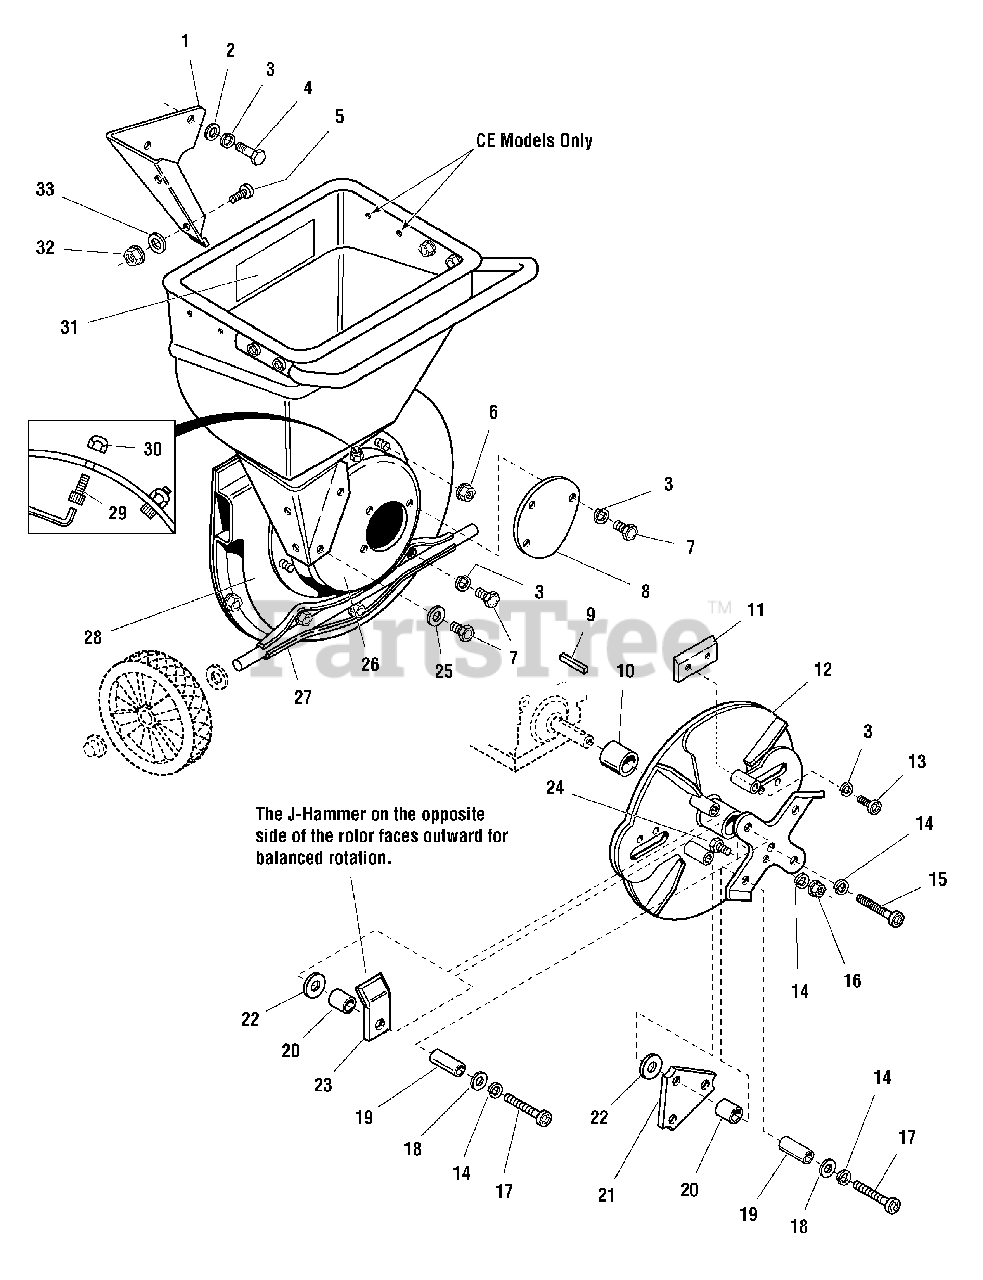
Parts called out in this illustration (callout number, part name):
1	HOPPER LINER
2	WASHER, Flat, 5/16
3	* LOCKWASHER, Split, 5/16
4	CAPSCREW, Hex Head, 5/16-18 x 3/4
5	CAPSCREW, Phillips Head, 1/4-20 x 5/8
6	NUT, Hex Flange, 5/16-18
7	CAPSCREW, Hex Head, 5/16-18 x 1/2
8	COVER, Rotor Housing
9	KEY, 1/4 Sq. x 2-1/4
10	SPACER, Rotor (5/14 Only)
10	SPACER, Rotor (8/14 Only)
11	CHIPPER KNIFE
12	* ROTOR, 1" Hub
13	CAPSCREW, Socket Head, 5/16-24 x 5/8
14	* LOCKWASHER, Split, 3/8
15	CAPSCREW, Socket Head, 3/8-24 x 2
16	NUT, Hex, 3/8-16
17	* CAPSCREW, Hex, Socket Head, w/Patch, 3/8 16 x 2, Gr. 8
18	* WASHER, Flat, 7/8 O.D.
19	* SPACER, Tube
20	* SPACER, 3/4" O.D., 3/4" Long (5/14 Only)
20	* SPACER, 1" O.D., 33/64" Long (8/14 0nly)
21	HAMMER, Triangular
22	WASHER, Plain, 1/2 x 1-1/4 x 3/16 (8/14 0nly)
24	CAPSCREW, Socket Head, 3/8-16 x 5/8
25	WASHER, Flat, 5/16
26	HOUSING, Rotor
27	AXLE ASSEMBLY
28	HOUSING, Fan
29	CAPSCREW, Socket Head, 5/16-18 x 1/2
30	NUT, Nylock, 5/16-18
31	DECAL, DANGER - Rotating Cutters/No Hands Below Line
32	NUT, Hex Flange Toplock, 1/4-20
33	WASHER, Flat, 1/4
